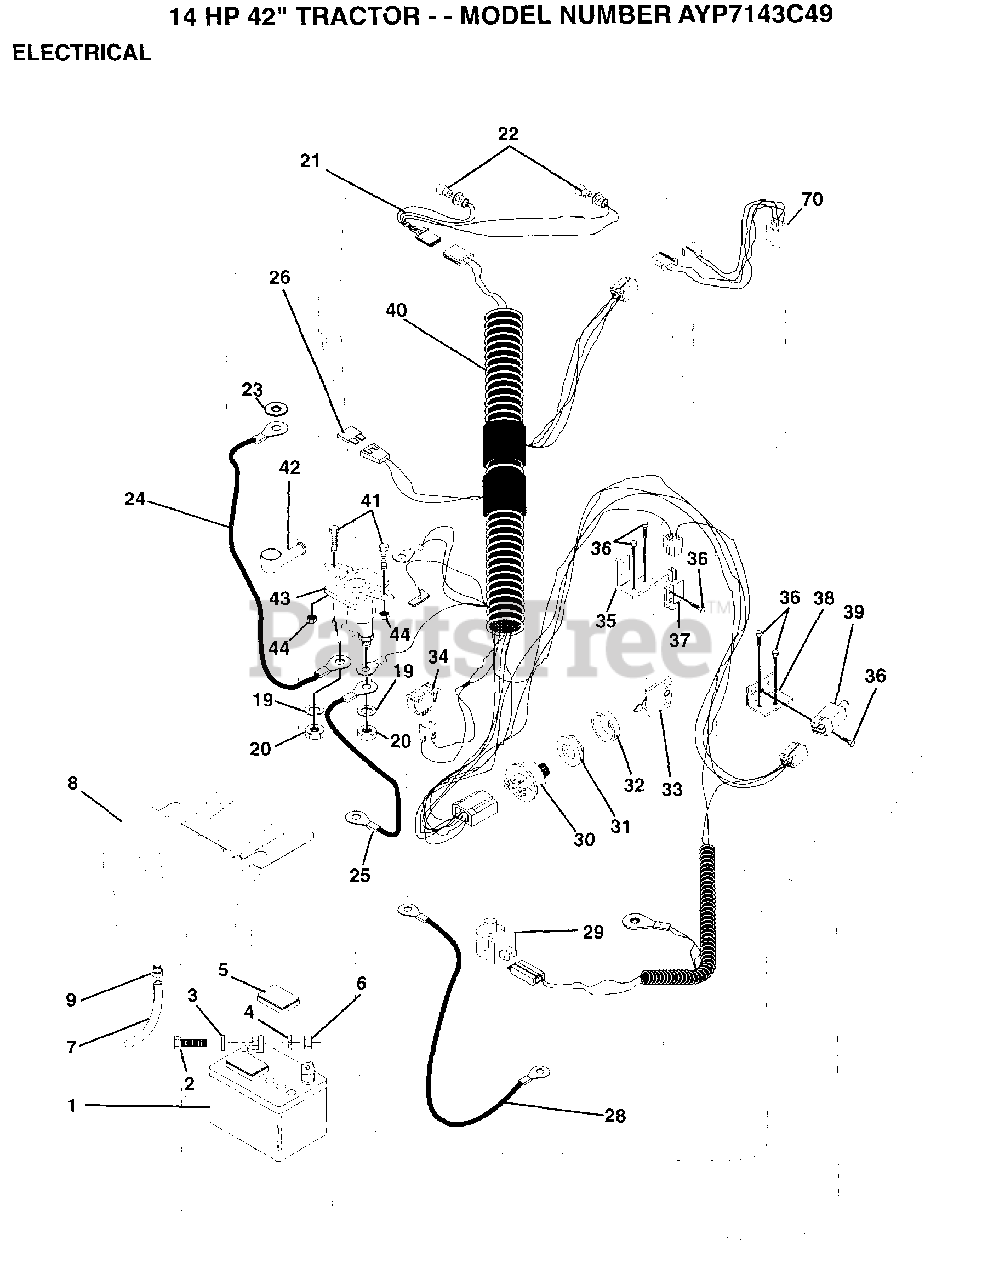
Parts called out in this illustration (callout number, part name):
2	BOLT LT
3	WASHER
4	LOCKWASHER
5	"CAP,BATTERY "
7	TUBE T
9	HOSE CLAMP T
20	NUT
21	"HARNESS,LIGHT SOC"
22	HEADLAMP BULB
23	LOCKWASHER
24	"CABLE T, BATTERY"
26	FUSE HYT
28	CABLE T
29	SWITCH SEAT
32	COVER KEY SWITCH
33	KEY STEEL DELTA
34	SWITCH LT
35	BRACKET LT
36	SCREW
37	SWITCH-INTER. GT
38	BRACKET SWITCH IN
39	SWITCH INTERLOCKT
40	HARNESS IGN DASH
41	BOLT HXHD FIN
44	NUT HXKEP 1/4X20
70	HARNESS.ENG.DUAL
